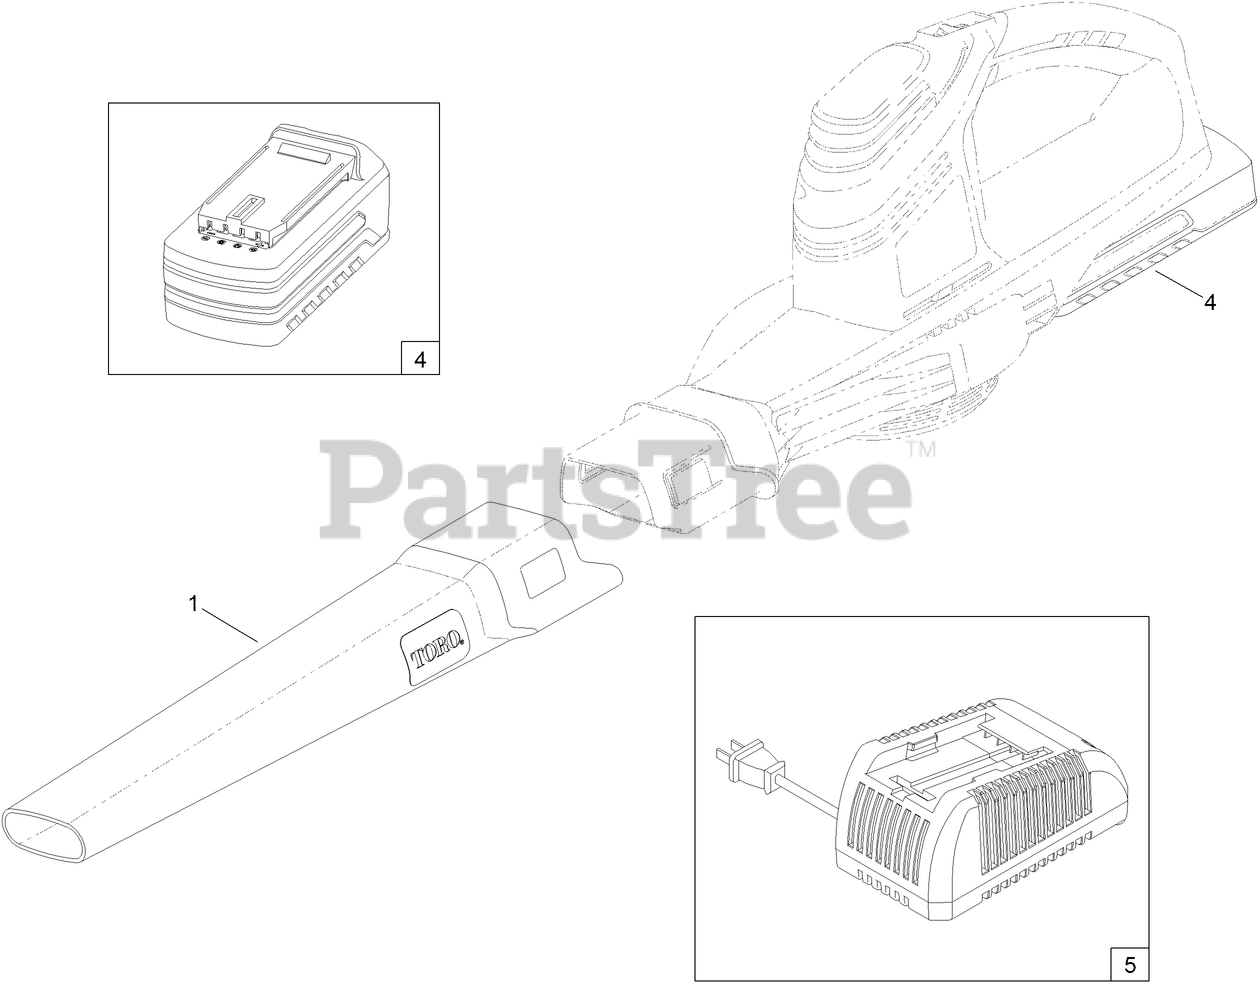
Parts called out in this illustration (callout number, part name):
1	TUBE-OUTLET, SWEEPER
4	BATTERY-LI ION, 20V MAX
5	CHARGER-20V MAX, LI ION
